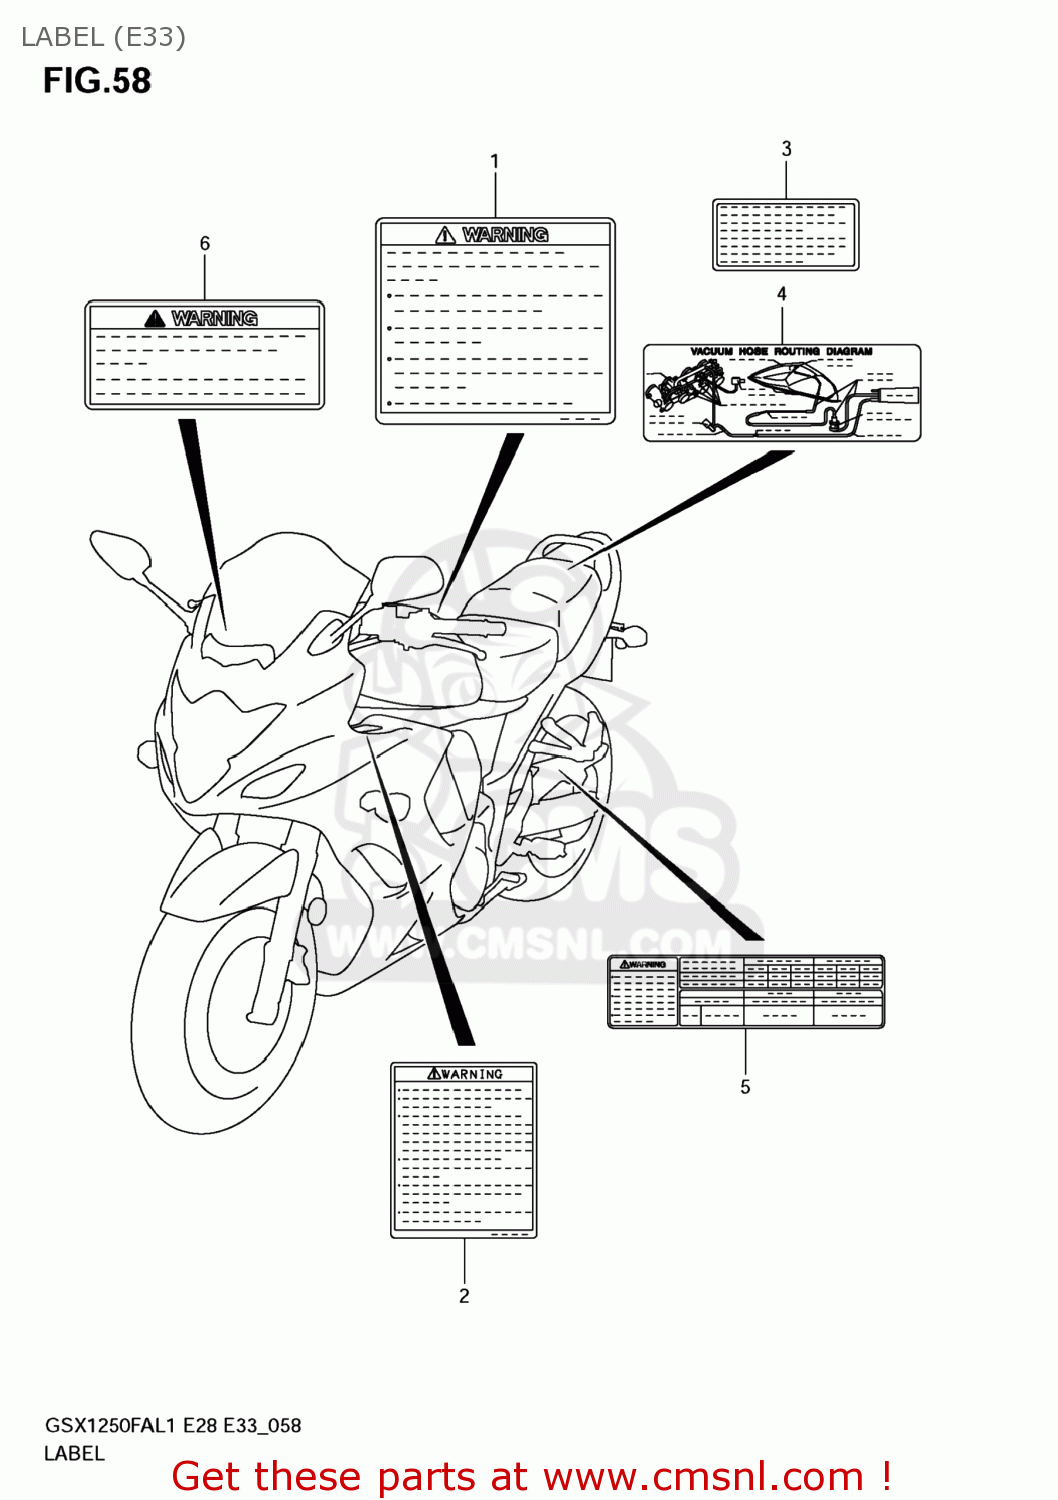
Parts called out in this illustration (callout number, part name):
1	LABEL,GENERAL WARNING
2	LABEL,SCREEN
3	LABEL,MANUAL NOTICE
4	LABEL,VACUUM HOSE ROUTING
5	LABEL,TIRE INFORMATION
6	LABEL,WARNING STEERING
7	MANUAL,OWNER'S
